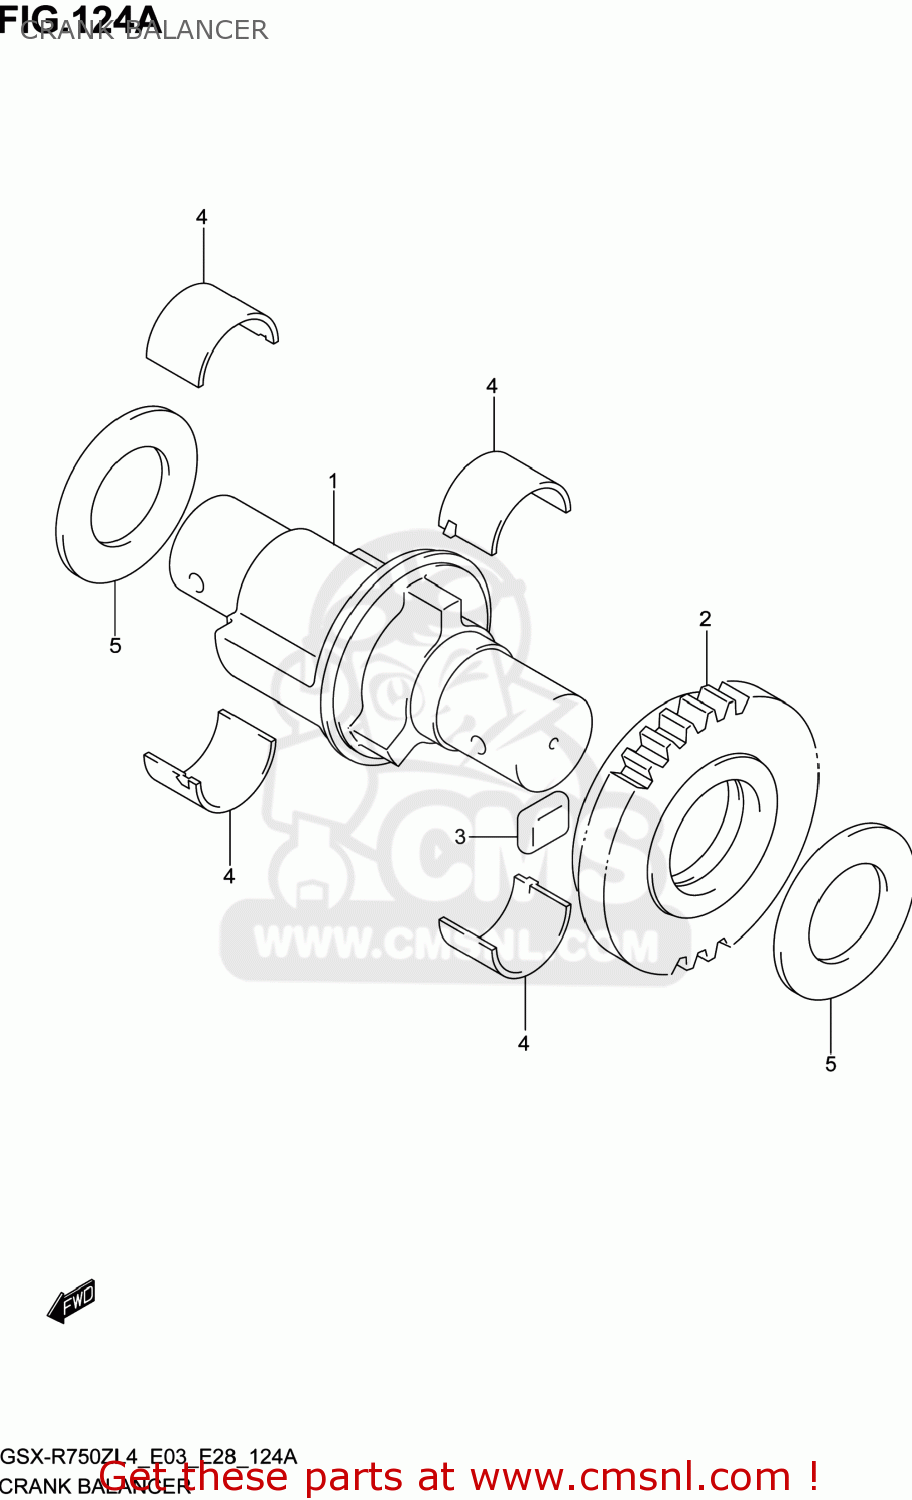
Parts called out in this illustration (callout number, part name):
1	BALANCER,CRANK
2	GEAR,CRANK BALANCER
3	DAMPER,CRANK BALANCER GEAR
4	BEARING,CRANK BALANCER
5	SHIM(23X40X2)
